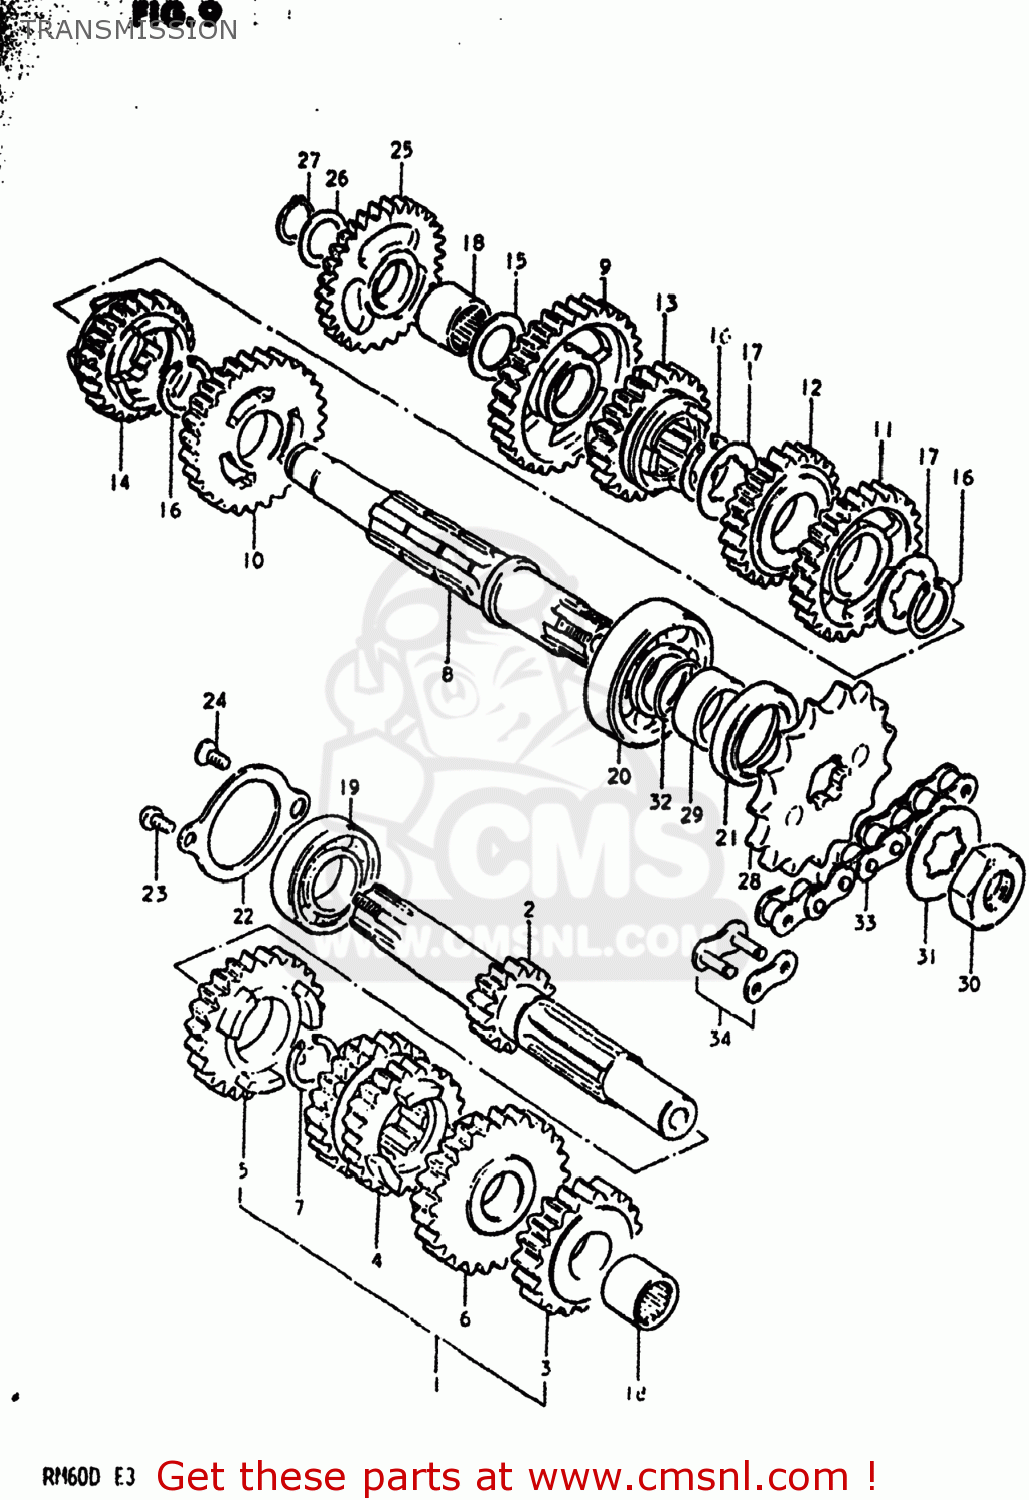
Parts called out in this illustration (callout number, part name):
1	SHAFT,COUNTER
2	SHAFT,COUNTER
3	GEAR,SECOND DRIVE
4	GEAR,THIRD/FOURTH DRIVE
5	GEAR,FIFTH DRIVE
6	GEAR,SIXTH DRIVE
7	CIRCLIP
8	SHAFT,DRIVE
9	GEAR,FIRST DRIVEN
10	GEAR,SECOND DRIVEN
11	GEAR,THIRD DRIVEN
12	GEAR,FOURTH DRIVEN
13	GEAR,4TH DRIVEN(NT:36)
14	GEAR,SIXTH DRIVEN
15	WASHER(13X24X1)
16	CIRCLIP
17	WASHER,LOCK
18	ROLLER BEARING (13X19X1
19	BEARING
20	BEARING
21	SEAL,OIL(21X35X5)
22	RETAINER,CNTR SHAFT BEARING
23	SCREW
24	SCREW
25	GEAR,KICK STARTER IDLE
26	WASHER
27	CIRCLIP
28	SPROCKET,ENGINE(NT:12)
29	SPACER (17X21X11)
30	NUT
31	WASHER,LOCK
32	O RING(D:1,ID:16.8)
33	CHAIN ASSEMBLY,DRIVE
34	JOINT ASSEMBLY,CHAIN
